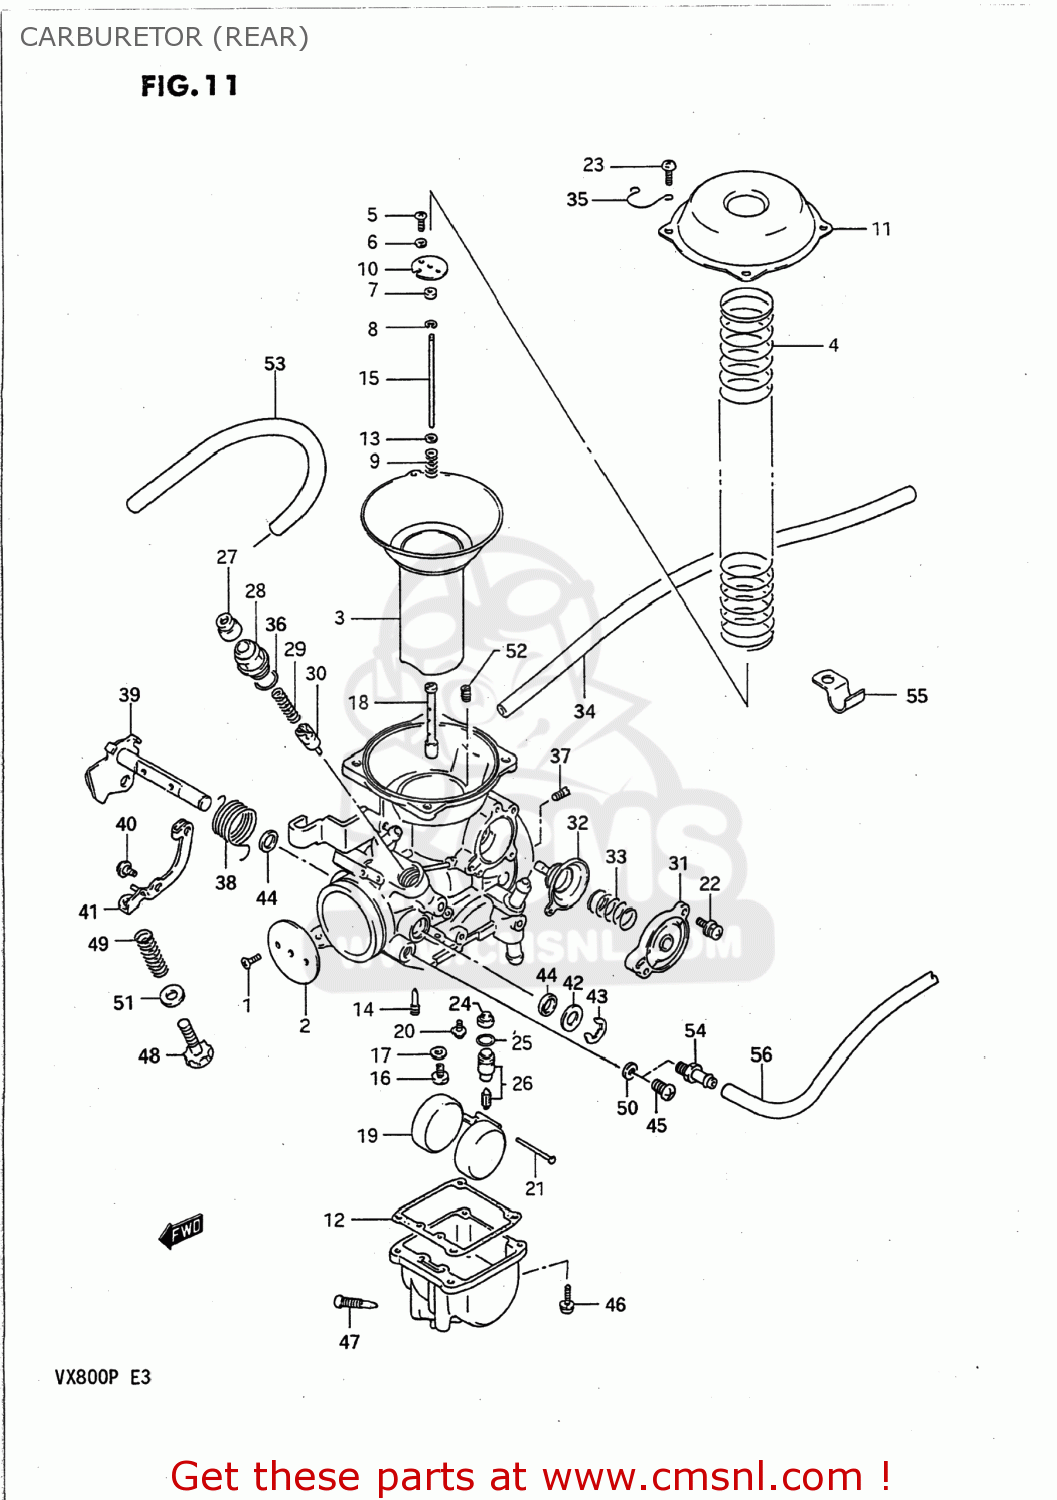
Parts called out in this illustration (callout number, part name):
1	SCREW
2	VALVE,THROTTLE
3	DIAPHRAGM,CARBURETOR
4	SPRING,DIAPHRAGM
5	SCREW
6	LOCK WASHER
7	RING
8	CLIP
9	SPRING
10	PLATE
11	COVER
12	GASKET,FLOAT CHAMBER (NAS)
13	WASHER
14	JET,PILOT(45)
15	NEEDLE JET
16	JET,MAIN(132.5)
17	WASHER,NEEDLE NOZZLE
18	JET,NEEDLE(P-7)
19	FLOAT
20	SCREW
21	PIN,FLOAT
22	SCREW
23	SCREW
24	FILTER
25	O-RING,NEEDLE VALVE
26	VALVE ASSY,NEEDLE
27	CAP
28	HOLDER,GUIDE
29	SPRING
30	PLUNGER,STARTER
31	COVER
32	DIAPHRAGM ASSY
33	SPRING
34	HOSE
35	CLIP
36	O RING
37	JET,AIR(65)
38	SPRING,SHAFT RETURN
39	SHAFT ASSEMBLY
40	SCREW
41	LEVER ASSEMBLY
42	GASKET,THROTTLE SHAFT (NAS)
43	E RING
44	SEAL,THROTTLE SHAFT
45	SCREW
46	SCREW
47	PLUG
48	ADJUSTER
49	SPRING
50	GASKET,DRAIN PLUG (NAS)
51	WASHER
52	JET,PILOT AIR(2.0)
53	HOSE
54	NIPPLE
55	CLAMP
56	HOSE (4.5X8.5X300)
